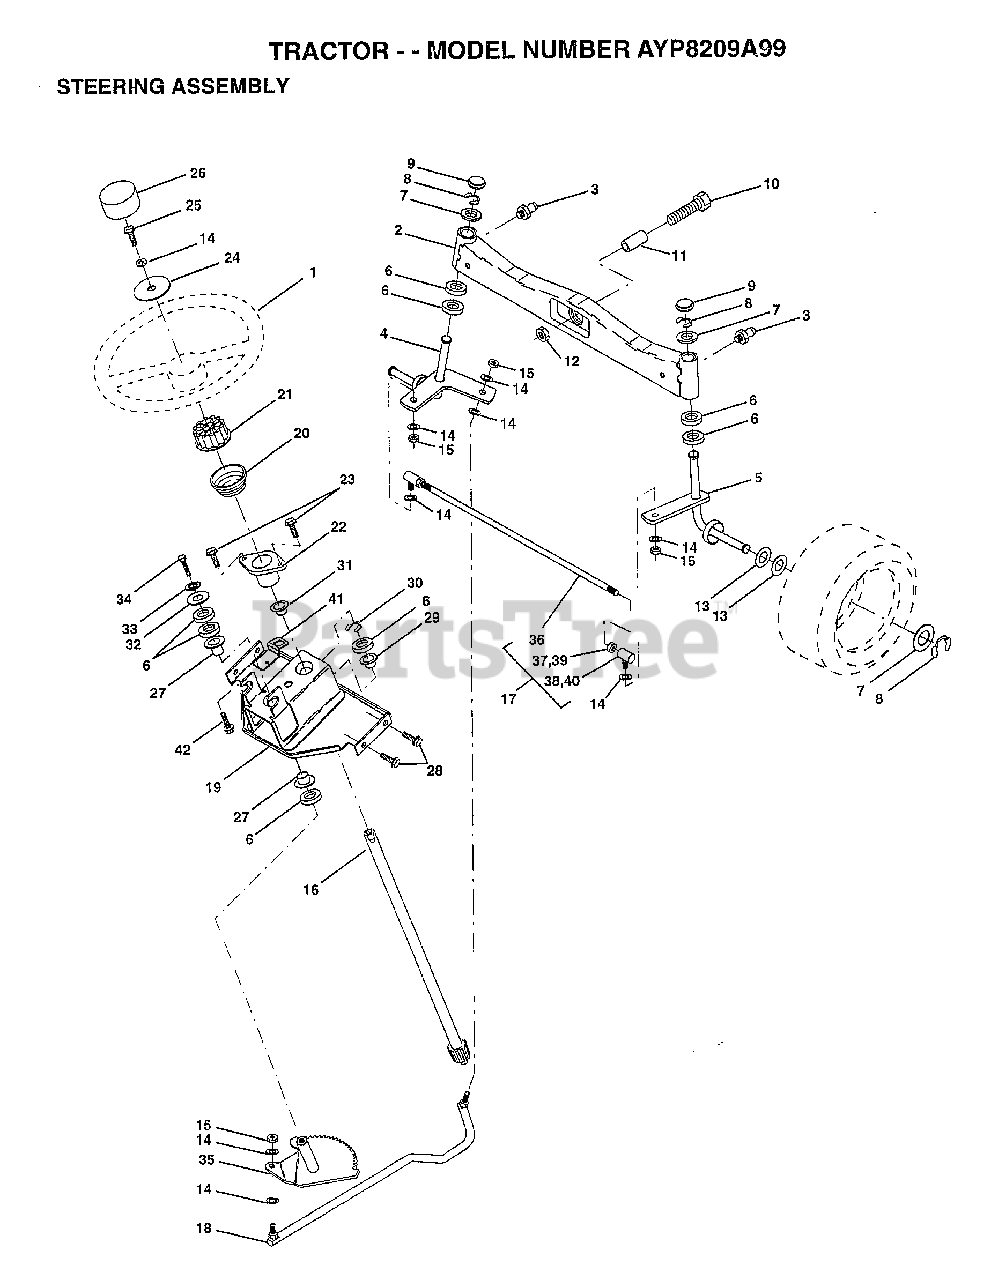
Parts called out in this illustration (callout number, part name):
3	ZERK M
4	SPINDLE ASM LH
5	SPINDLE ASM RH
6	WASHER .T
7	WASHER
8	RING
9	CAP
10	BOLT
11	SPACER BEARING
12	"NUT-LOC,FLANGE LT"
13	WASHER
14	LOCKWASHER
15	GRIPCO NUT
16	SHAFT.STEER.VGT
17	ROD.ASM.TIE.BALL
18	DRAGLINK.BALL.JOI
19	SUPPORT ASM-STEER
20	COLUMN.STEERING
21	ADAPTER LT
22	"BUSHING,STEERING"
23	"SCREW-TT,10-32 FL"
24	WASHER T
25	BOLT
26	"INSERT,STR WHEEL"
27	COL. SRTG. BEAR.
28	SCREW
29	"FLANGE GT, BEAR."
30	KLIP RING
31	BUSHING.NYLINER.
32	WASHER
33	LOCKWASHER
34	BOLT
35	GEAR.ASM.SECTOR.
37	NUT
38	JOINT.RH
39	NUT
40	JOINT.LH
41	"BRKT-SW, INTER"
42	SCREW LT
